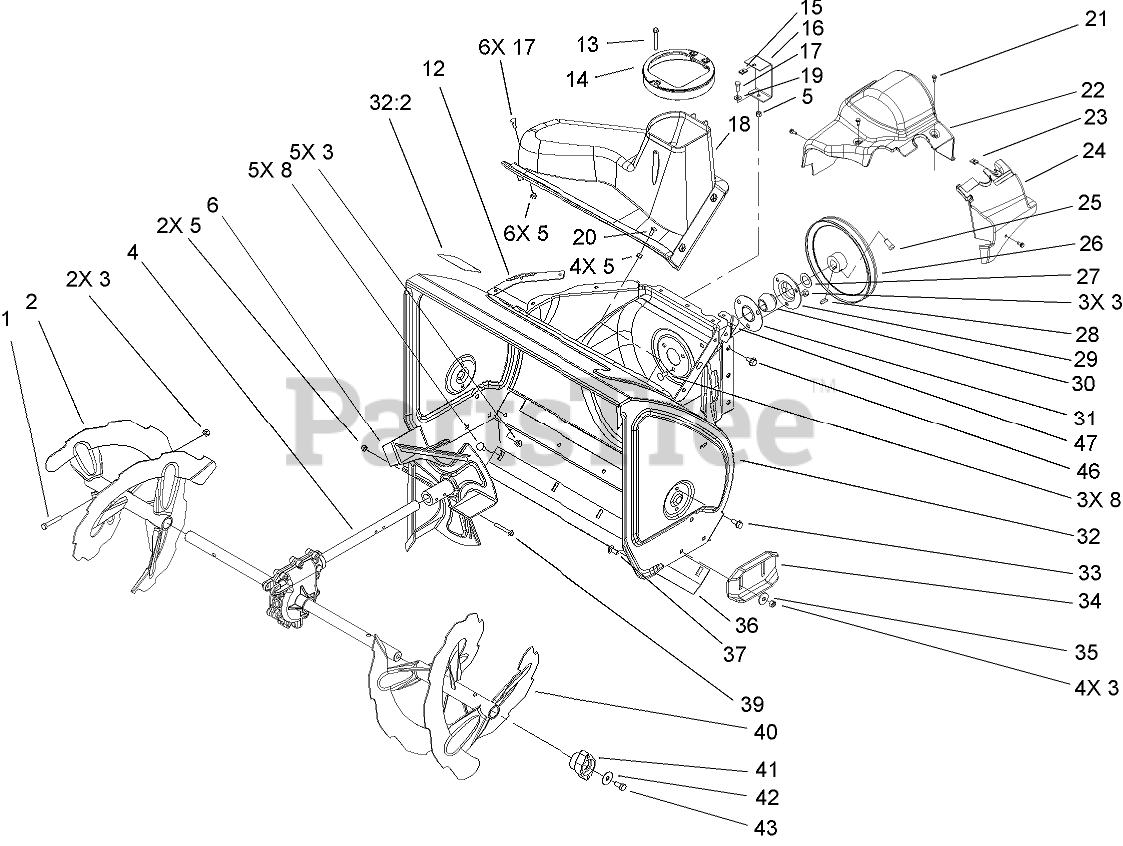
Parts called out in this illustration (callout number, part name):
1	SCREW-HH
2	RH AUGER ASM
3	NUT-LOCK, NI
4	AUGER GEARCASE ASM
5	NUT-LOCK, NI
6	IMPELLER ASM
8	SCREW-CARR
12	SEAL-FLANGE, COVER
13	SCREW-PLASTITE
14	GUIDE-CHUTE
15	NUT-SPEED, U-TYPE
16	BRACKET-COVER, CLIP NUT
17	SCREW-HH
19	WASHER-FLAT
20	BOLT-CARR
21	SCREW-HWH
22	COVER-BELT
23	NUT-SPEED
24	COVER-EXTENSION, BELT
25	SCREW-SET, SQH
26	PULLEY-IMPELLER
27	WASHER-THRUST
28	KEY-WOODRUFF
29	FLANGE-CUP, BEARING
30	BEARING-BALL
31	FLANGE-CUP, BEARING
32	HOUSING-AUGER, 28 INCH
32:2	DECAL-DANGER, AUGER
33	SCREW-HWHTF
35	WASHER
36	SCRAPER-FIXED
37	SCREW-CARR
39	SCREW-HHF
40	LH AUGER ASM
41	BEARING-AUGER
42	WASHER
43	SCREW-HH
46	SCREW-HWHTF
